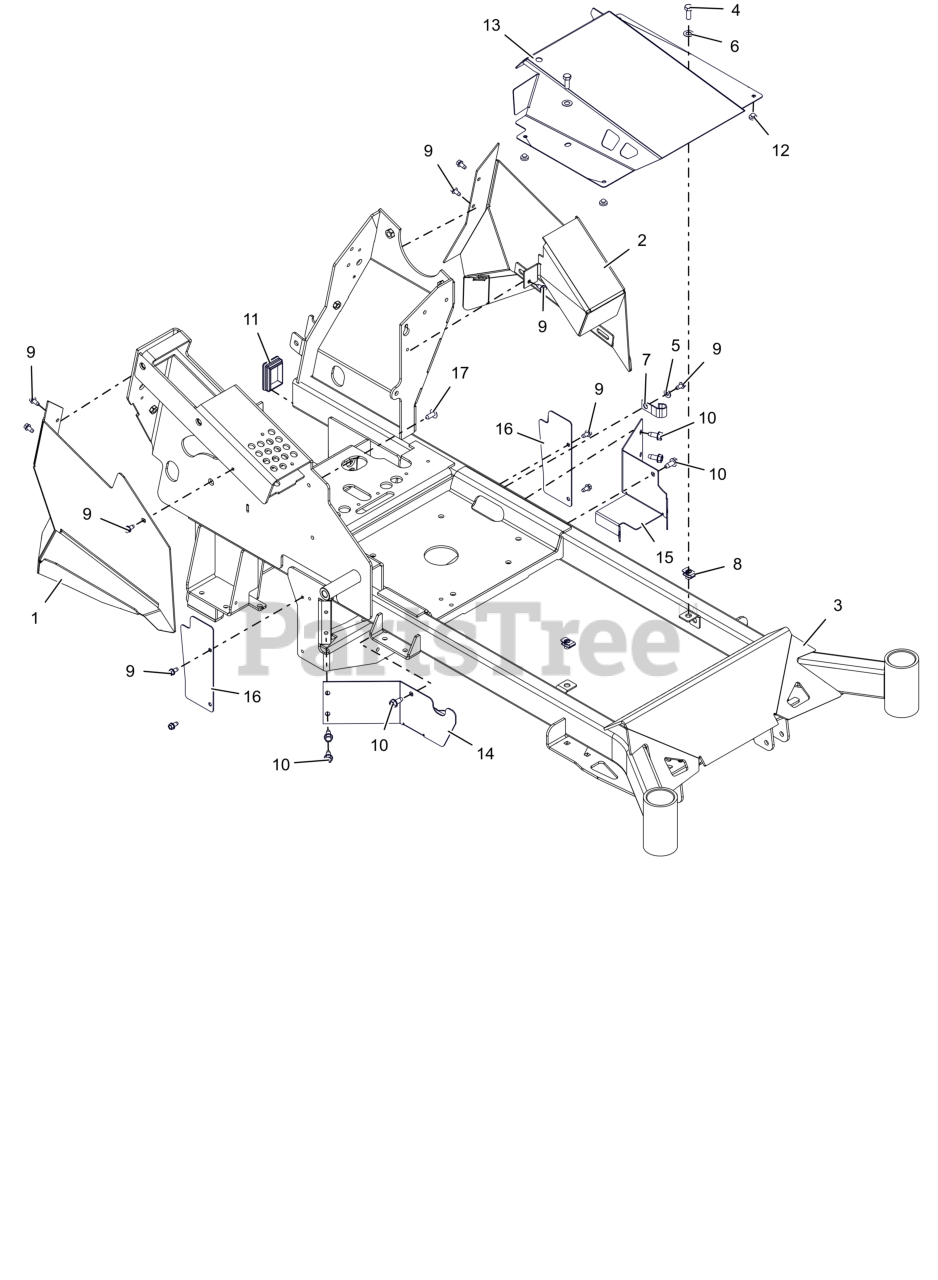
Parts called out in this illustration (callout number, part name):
1	WLDMT, RH 32-36" FENDER (BLACK)
2	WLDMT, LH FENDER (BLACK)
3	WLDMT, ARROW 32" - 36" FRAME (ORANGE)
4	BLT, HEX .31-18X.875 G5 ZCC
5	WSHR,FLT .281X.625X.065 ZCC
6	WSHR, FLT .385X.745X.030 ZCC
7	J-CLAMP
8	NUT-CLIP RETAINER 5/16-18X.56
9	SCR-TAP .25-20X.50 HWH ZCC
10	SCR,TAP .312-18X.75 HWH TR ZCC
11	PLUG, RECT 1.575 x 2.362
12	BUMPER GROMMET
13	COVER, BELT CE (ORANGE)
14	BRKT, TRANSAXLE GUARD RH (BLACK)
15	BRKT, TRANSAXLE GUARD LH (BLACK)
16	TRANSAXLE CE GUARD (BLACK)
17	XMAS TREE FASTNER-BLACK
